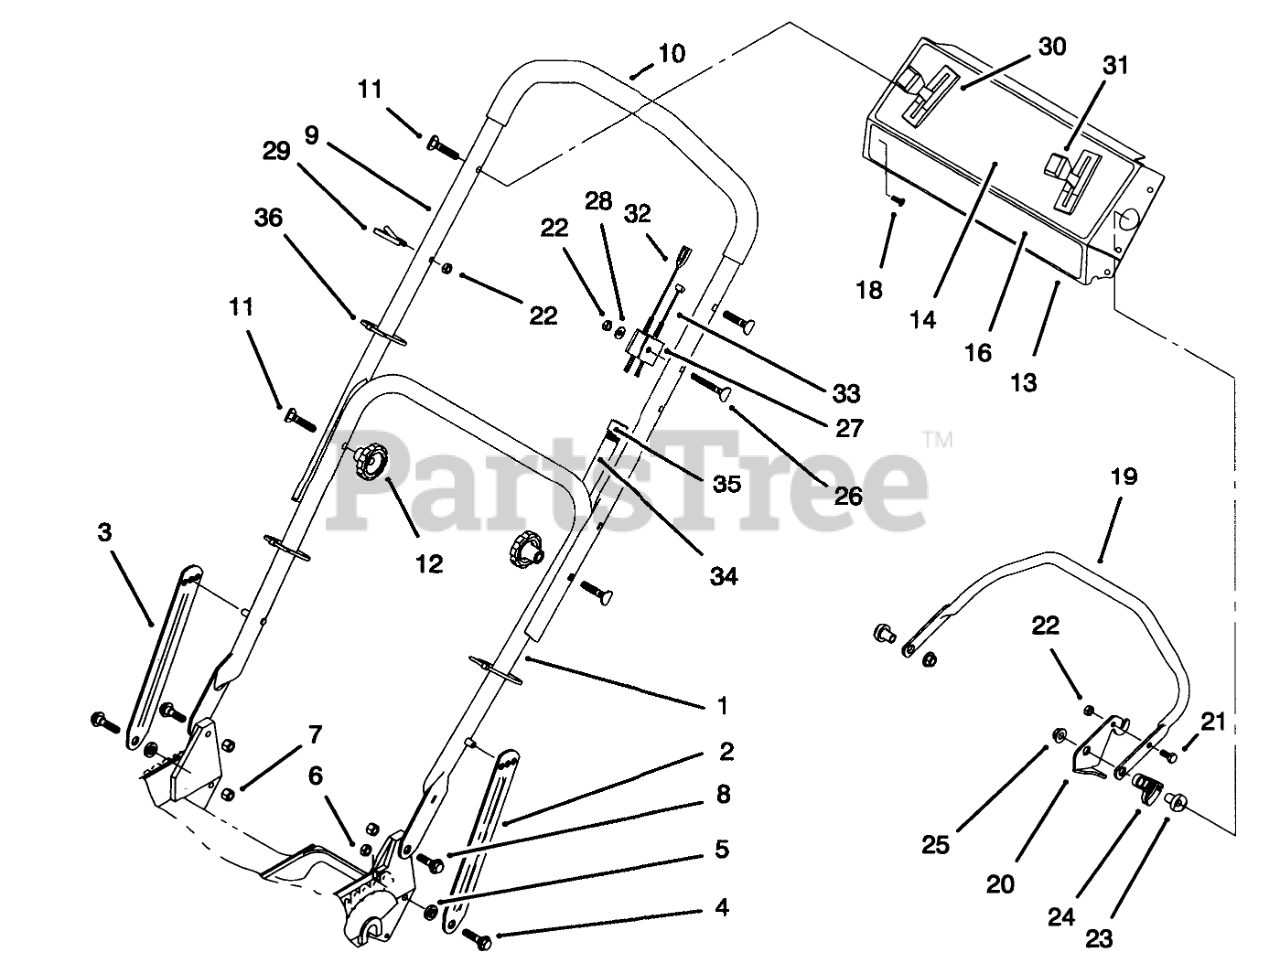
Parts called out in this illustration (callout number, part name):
1	ASM-Handle
2	Latch-Handle
3	Latch-Handle
4	SCREW-SHOULDER
5	SPACER
6	NUT-LOCK, NI
7	Nut-Lock
8	SCREW-SHOULDER
9	Handle-Upper
10	Grip-Foam
11	SCREW-HANDLE
13	Panel-Control (Incl. Ref. #14)
14	DECAL - INSTRUCTION
16	DECAL - CONSOLE
18	SCREW-TAP
19	Bar-Control
20	Lever-Control
21	SCREW-HH
22	NUT-LOCK, NI
23	SPACER-SUPPORT
24	LEVER-TRACTION
25	NUT-LOCK NI
26	SCREW-HANDLE
27	SUPPORT-CABLE
28	WASHER-FLAT
29	GUIDE-ROPE
30	CONTROL-SPEED, GROUND
31	THROTTLE CONTROL
32	BRAKE CONTROL
33	CABLE-TRACTION
34	CONTROL CABLE COVER
35	FITTING-RING
36	TIE-CABLE
